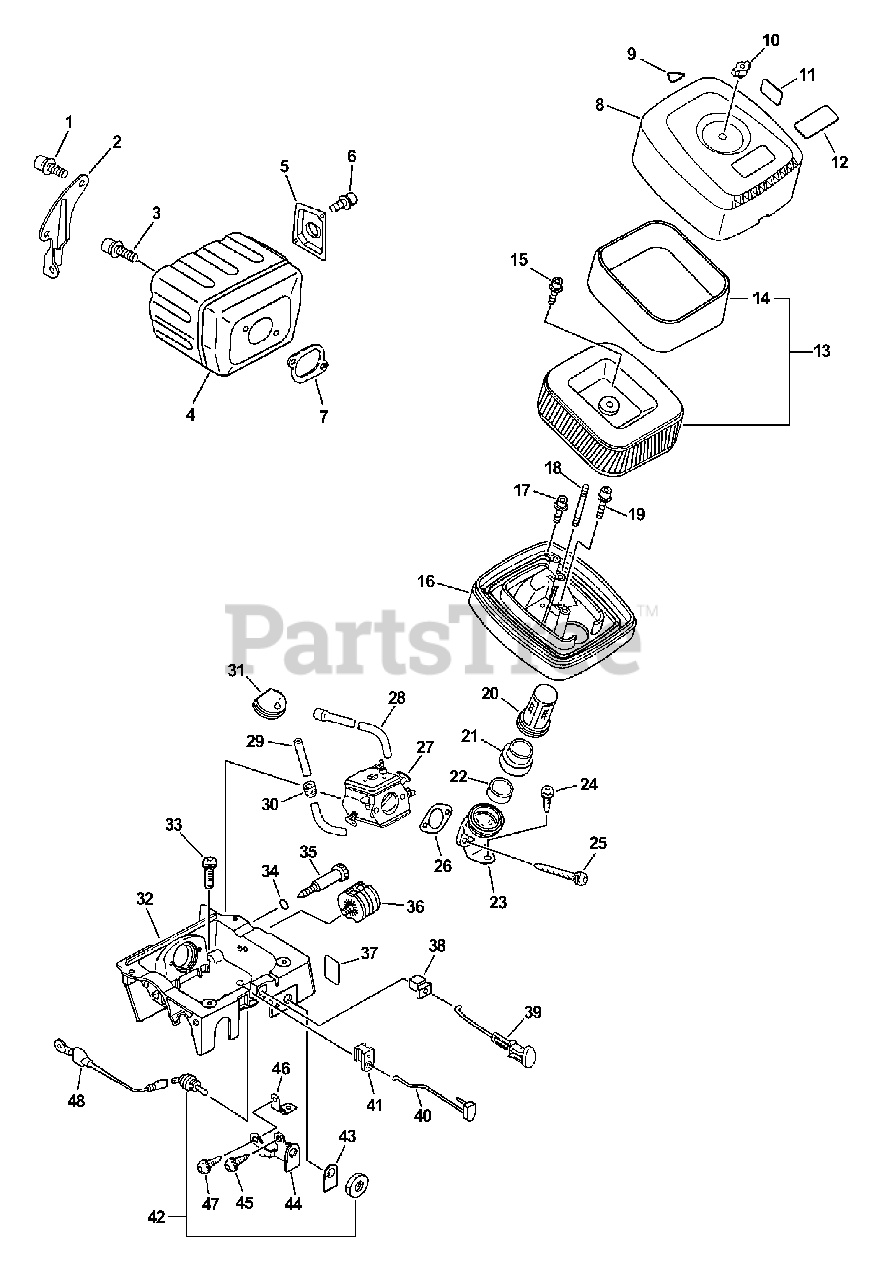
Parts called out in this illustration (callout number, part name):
1	SCREW - 5X14
2	BRACKET, MUFFLER
3	SCREW - 5X20
4	MUFFLER
5	GUIDE, EXHAUST
6	SCREW - 4X10
7	GASKET, EXHAUST
8	COVER, AIR FILTER
10	NUT
11	LABEL - CAUTION
12	LABEL - MODEL CSG-680
13	FILTER, AIR
14	FILTER, AIR
15	SCREW - 5X16
16	CASE, AIR FILTER
17	SCREW - 5X16
19	SCREW - 5X25
20	SCREEN, DEBRIS
21	CUSHION
22	COLLAR - 22
23	ADAPTOR, INTAKE
24	SCREW - 5X14
25	SCREW - 5X55
26	GASKET, INTAKE
27	CARBURETOR HDA-216
28	PIPE - IMPULSE
29	PIPE - 3X6X130
30	GROMMET
31	GROMMET
32	CASE, CARBURETOR
33	SCREW - 5X20
34	O-RING - 7
35	SCREW, IDLE ADJUST
37	LABEL - IDLE
39	ROD, CHOKE
40	ROD, THROTTLE
41	GUIDE, THROTTLE ROD
42	IGNITION SWITCH ASSY
43	LABEL - SWITCH
44	BRACKET, SWITCH
45	SCREW - 5X10
46	TERMINAL - GROUND
47	SCREW - 4X10
48	LEAD - GROUND
